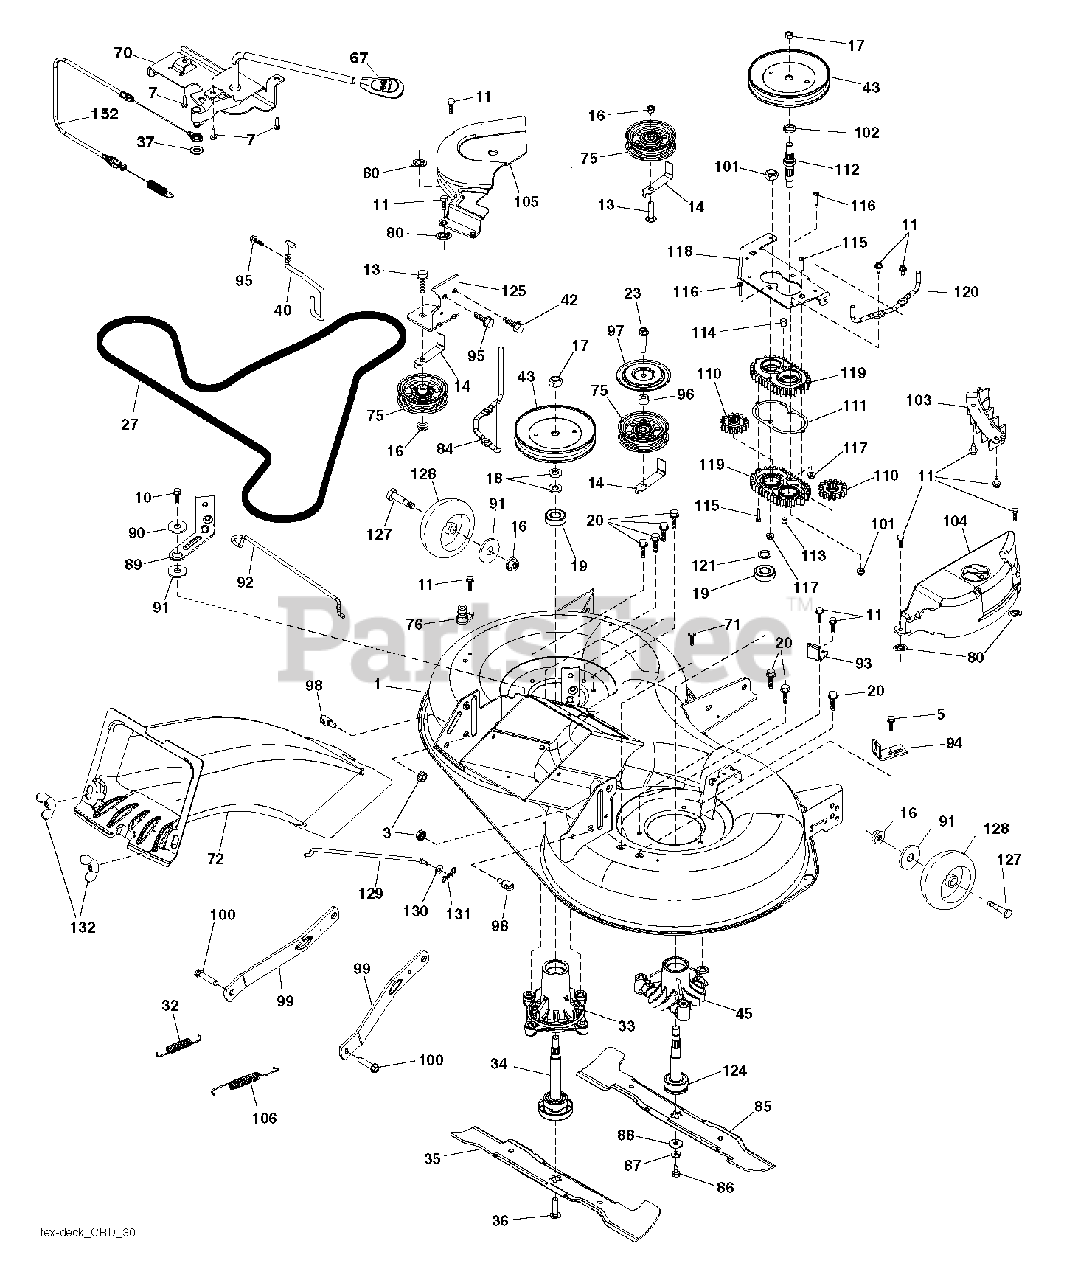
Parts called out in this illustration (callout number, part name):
3	NUT LOCK HEX FLANGE 5/16-18
5	BOLT.5/16HEX.WHS.HD
7	SCREW.#10 X 0.750.BOS THREAD
10	SCREW 3/8-16X1
11	SCREW.1/4-20X5/8
13	BOLT.3/8-16X1.50
14	KEEPER, BELT IDLER
16	NUT LOCK FLG 3/8-16 UNC
17	NUT.FLANGE.LOCK.TOP
18	WASHER.SPACER.MANDREL
20	SCREW, WASHER HEAD
23	SCREW LT
32	SPRING RETURN
33	HOUSING MANDREL
34	SHAFT.ASM.MDRL.N/GREASE.38
35	BLADE.3N1.LH.CRD.97
36	BOLT.WASHER.ASM.7/16-2
40	KEEPER BELT ENGINE LH
42	SCREW
43	PULLEY.MANDREL.5.438.PD
45	HOUSING.MANDREL
67	HANDLE.CLUTCH.CABLE.LT
70	CLUTCH.ASM.MANUAL.LT.PRED
71	SCREW 3/8-16X1/2
75	FLAT IDLER PULLEY
76	PORT.WASHOUT
80	PALNUT 1/4
84	KEEPER.BELT.MANDREL.PULLEY
85	BLADE.3N1.RH.CRD.97
87	LOCKWASHER
88	WASHER.BLADE
90	SPACER.RETAINER
94	BRKT.CLUTCH.CABLE
95	SCREW, 3/8-16X3/4
98	STUD.FASTNER.W/ANTI-ROTATE
99	ARM.SUSPENSION.MOWER.R
100	BOLT.SHOULDER
102	SPACER BEARING
106	SPRING.BRAKE.RETURN.38"
117	NUT T
127	BOLT.SHOULDER.3/8-16X3-5/8
128	WHEEL. GUAGE RALLY
129	ROD.ANTI.SWAY.48/54"K4
130	WASHER
131	PIN.COTTER.5/16.BOW TI
132	KNOB.HANDLE.3/8.TRI-POINT.BLAC
